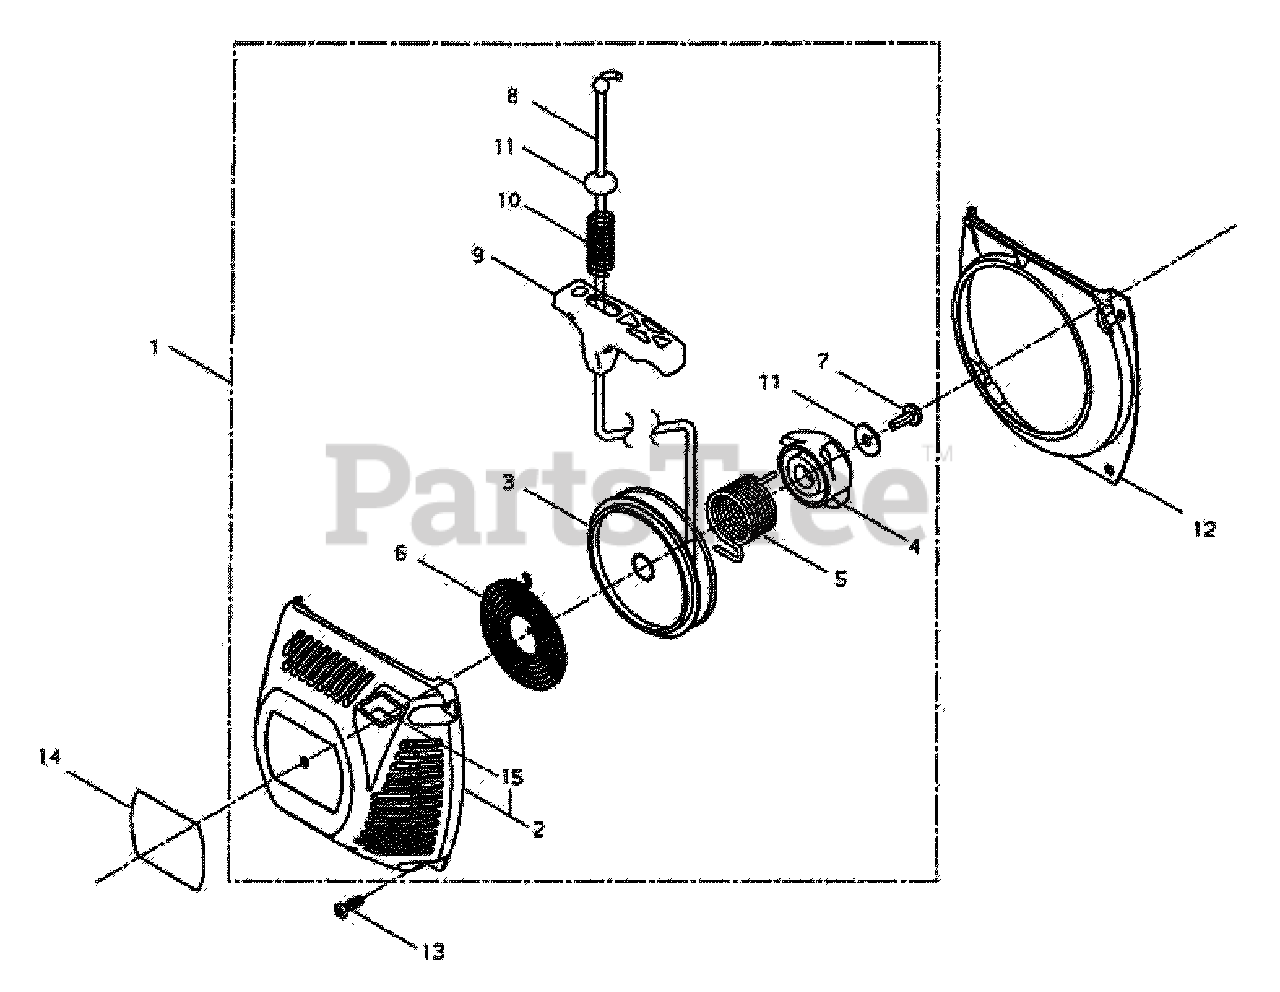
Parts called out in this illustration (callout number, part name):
1	STARTER ASSY
2	CASE, STARTER
3	REEL, ROPE
4	CATCHER, PAWL
5	SPRING
6	SPRING, REWIND
7	SCREW
8	ROPE, STARTER - 3.8X750
9	GRIP, STARTER
10	SPRING
11	COLLAR
12	DEFLECTOR, AIR
13	SCREW - 4X20
14	LABEL - MODEL
15	GUIDE, ROPE
